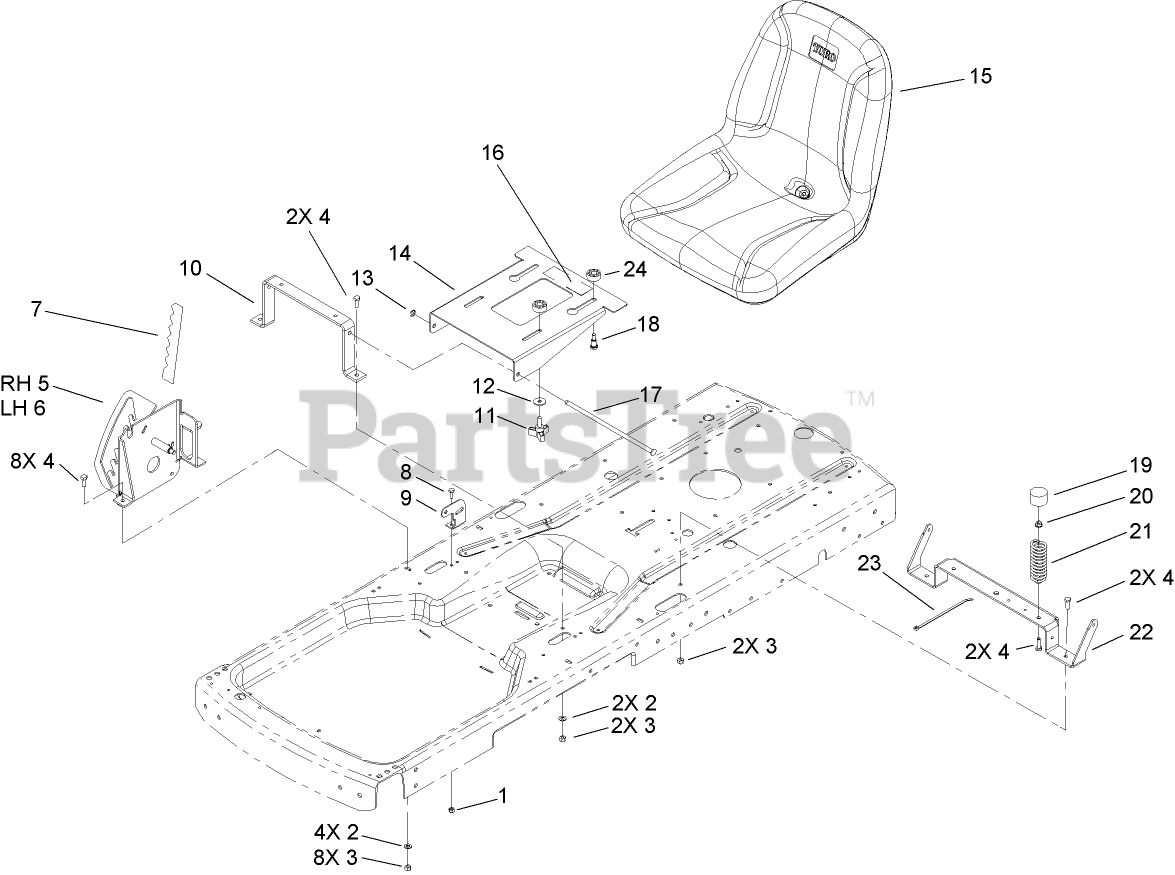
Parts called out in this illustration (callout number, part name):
1	NUT-LOCK, NI
2	WASHER-PLAIN
3	NUT-LOCK, NI
4	SCREW-HH
5	RH PLATE ASM
6	LH PLATE ASM
7	DECAL-HOC
8	SCREW-HH
9	BRACKET-BELLCRANK
10	BRACE-SEAT, FRONT
12	WASHER-PIVOT
13	E-RING
14	BRACKET-SEAT
16	DECAL-SERVICE, CE
17	PIN-PIVOT
18	SCREW-SHOULDER
19	CAP-PROTECTOR
20	NUT-HF
21	SPRING-COMPRESSION
22	BRACE-SEAT, REAR
23	TIE-CABLE
24	SPACER-NYLON
